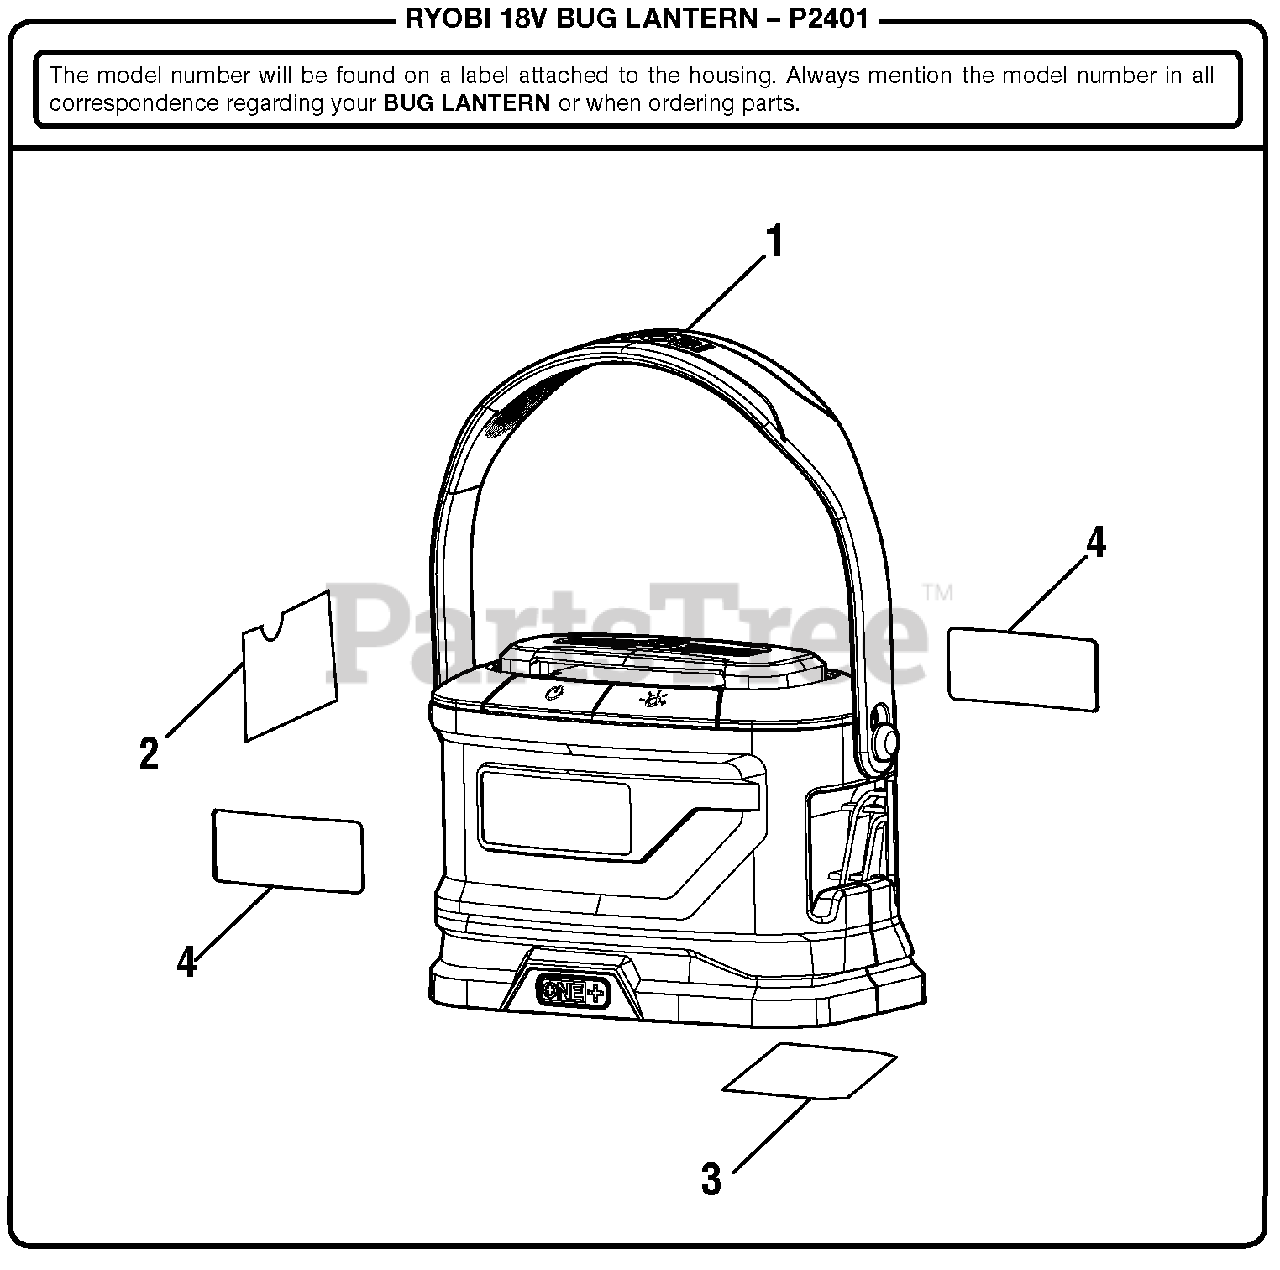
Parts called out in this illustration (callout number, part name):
2	Warning Label
3	Data Label
4	Logo Label
